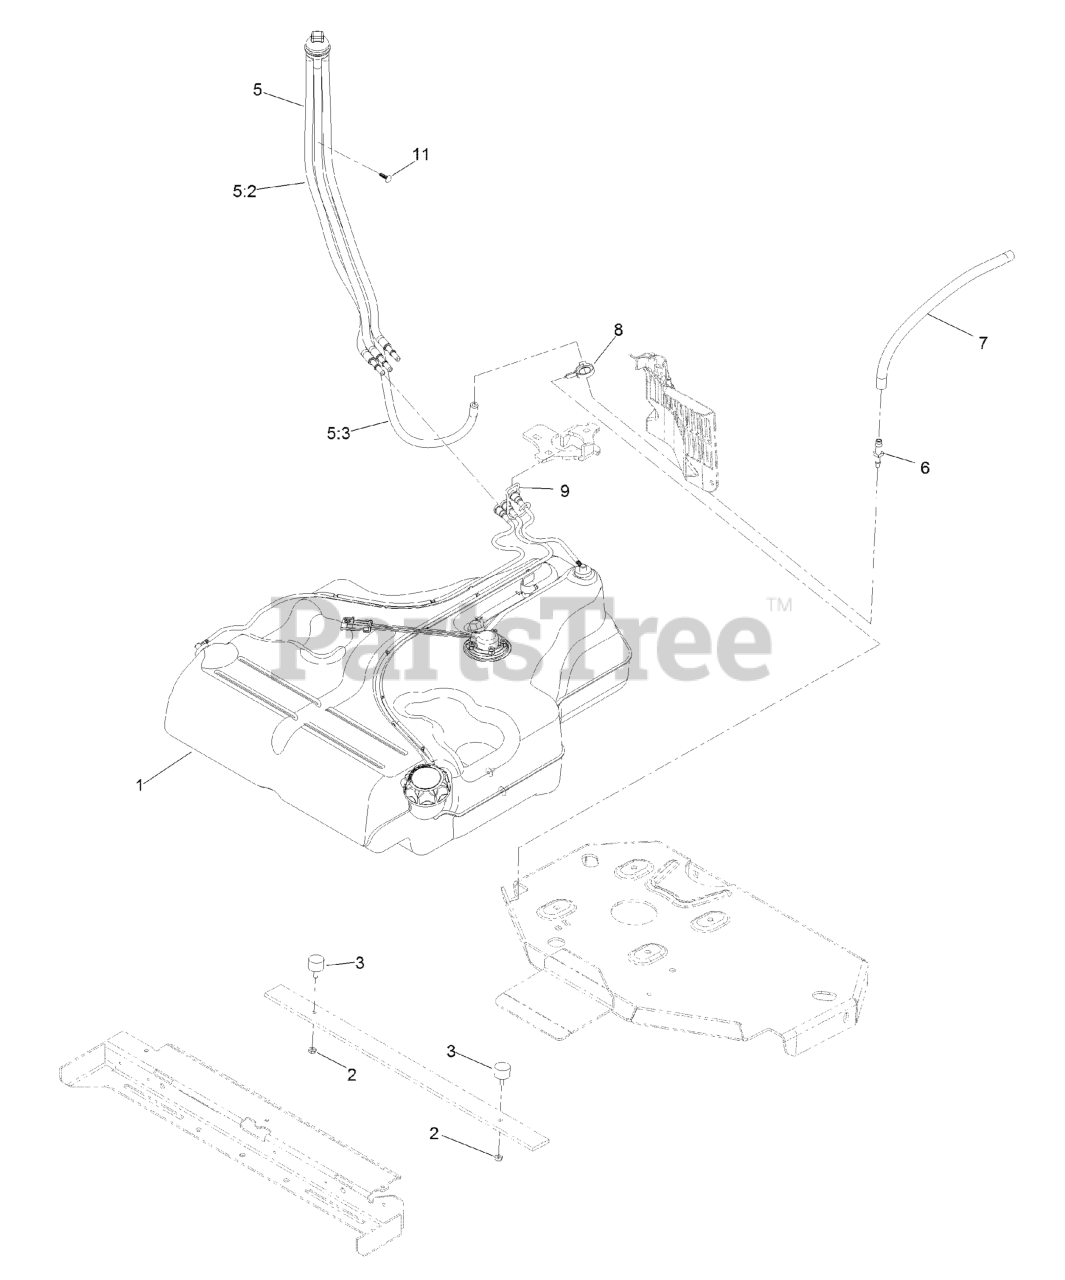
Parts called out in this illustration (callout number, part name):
2	NUT-JAM
4	HOSE ASM
5	FUEL MANIFOLD VENT ASM
6	FITTING-STRAIGHT
7	HOSE-FUEL
8	CLAMP-HOSE
9	RETAINER-LINE, VAPOR
